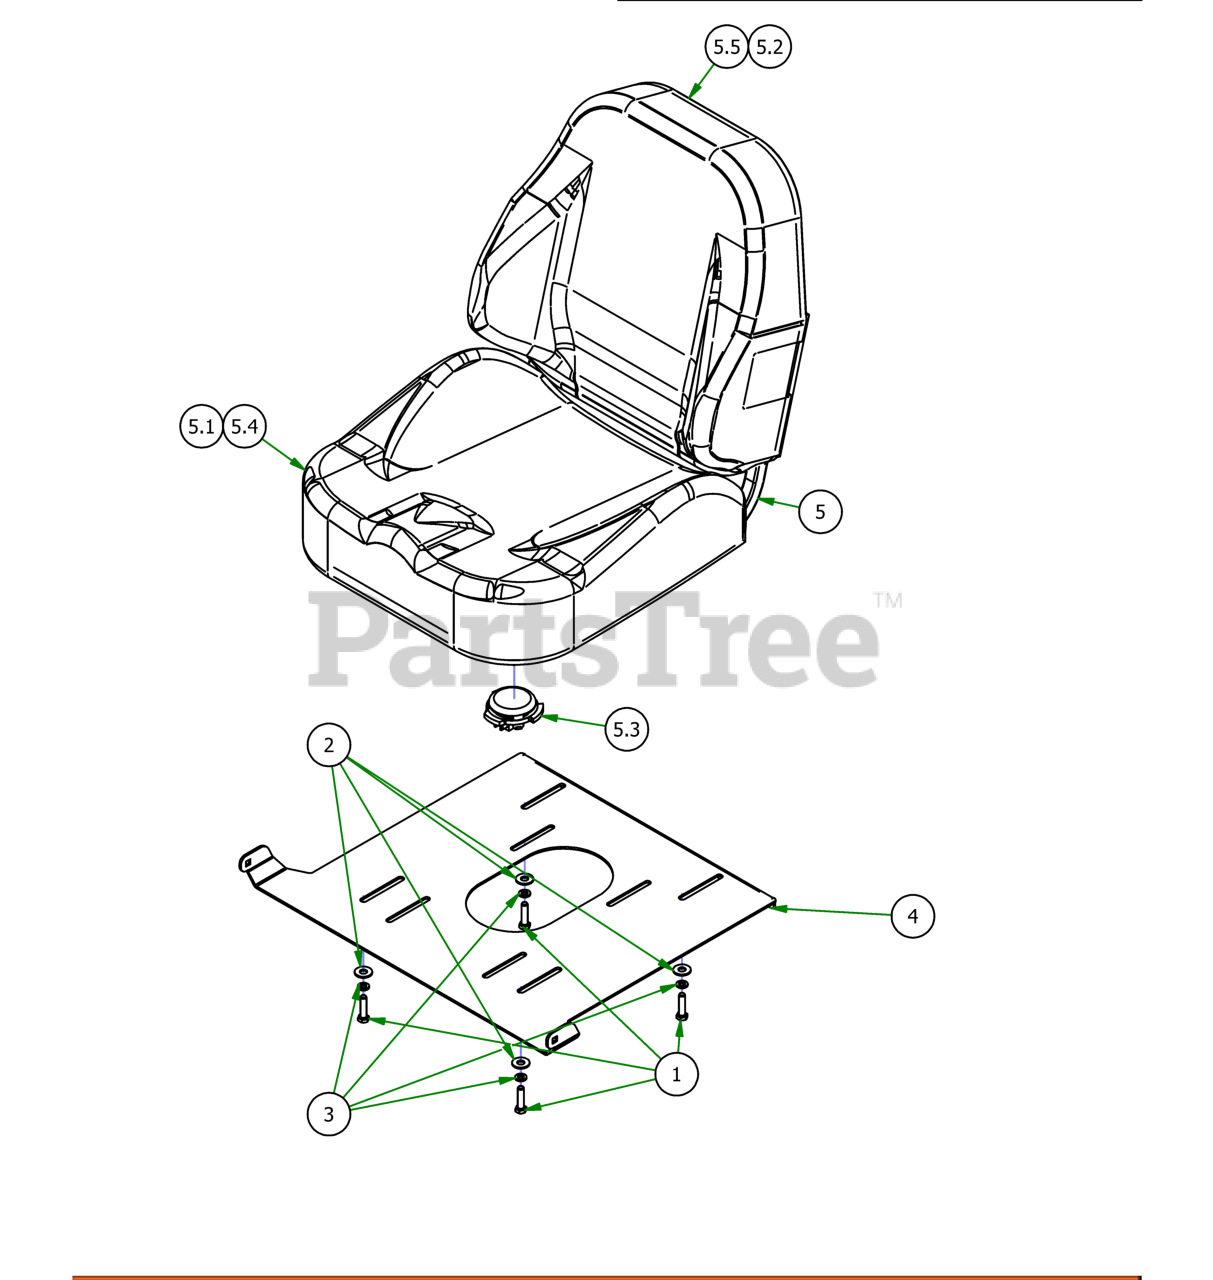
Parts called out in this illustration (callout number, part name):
1	5/16-18 X 1-1/4 HEX C/S (GR.5) ZC
2	5/16 USS FLAT WASHER (7/8 OD) ZINC
3	5/16 SPLIT LOCKWASHER ZINC
4	2017 MZ Seat Plate
5	2021 Avenger Seat
5.1	Seat Cover Molded Foam for 071-2040-18/071-5080-18
5.2	Foam Molded Back for 071-2100-00
5.3	13/14 MZ/Outlaw Seat Switch
5.4	2020 ZT Elite Seat Cover for 071-2040-20
5.5	Backrest Seat Cover for 071-2040-20
